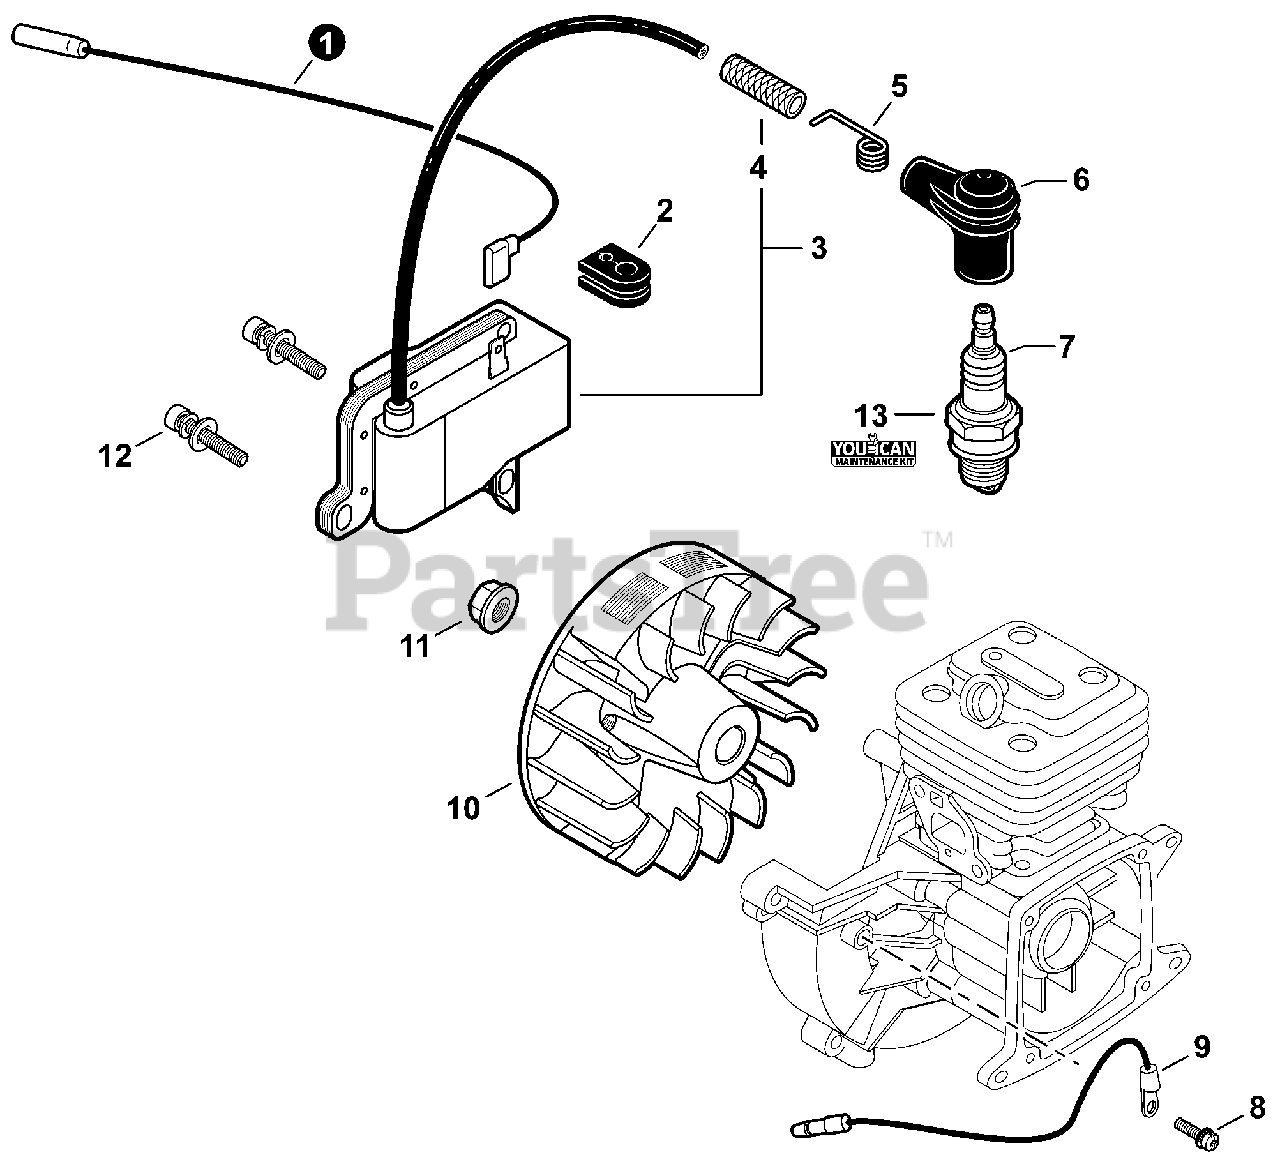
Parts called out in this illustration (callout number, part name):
1	LEAD - IGNITION 145 MM
3	COIL SET, IGNITION
4	TUBE, INSULATOR
5	TERMINAL, SPARK PLUG
6	CAP, SPARK PLUG
7	SPARK PLUG - BPMR8Y
8	SCREW 5×10
9	LEAD - GROUND
10	FLYWHEEL
11	NUT, FLANGE M8
12	BOLT 5×16
13	TUNE-UP KIT - YOUCANT
